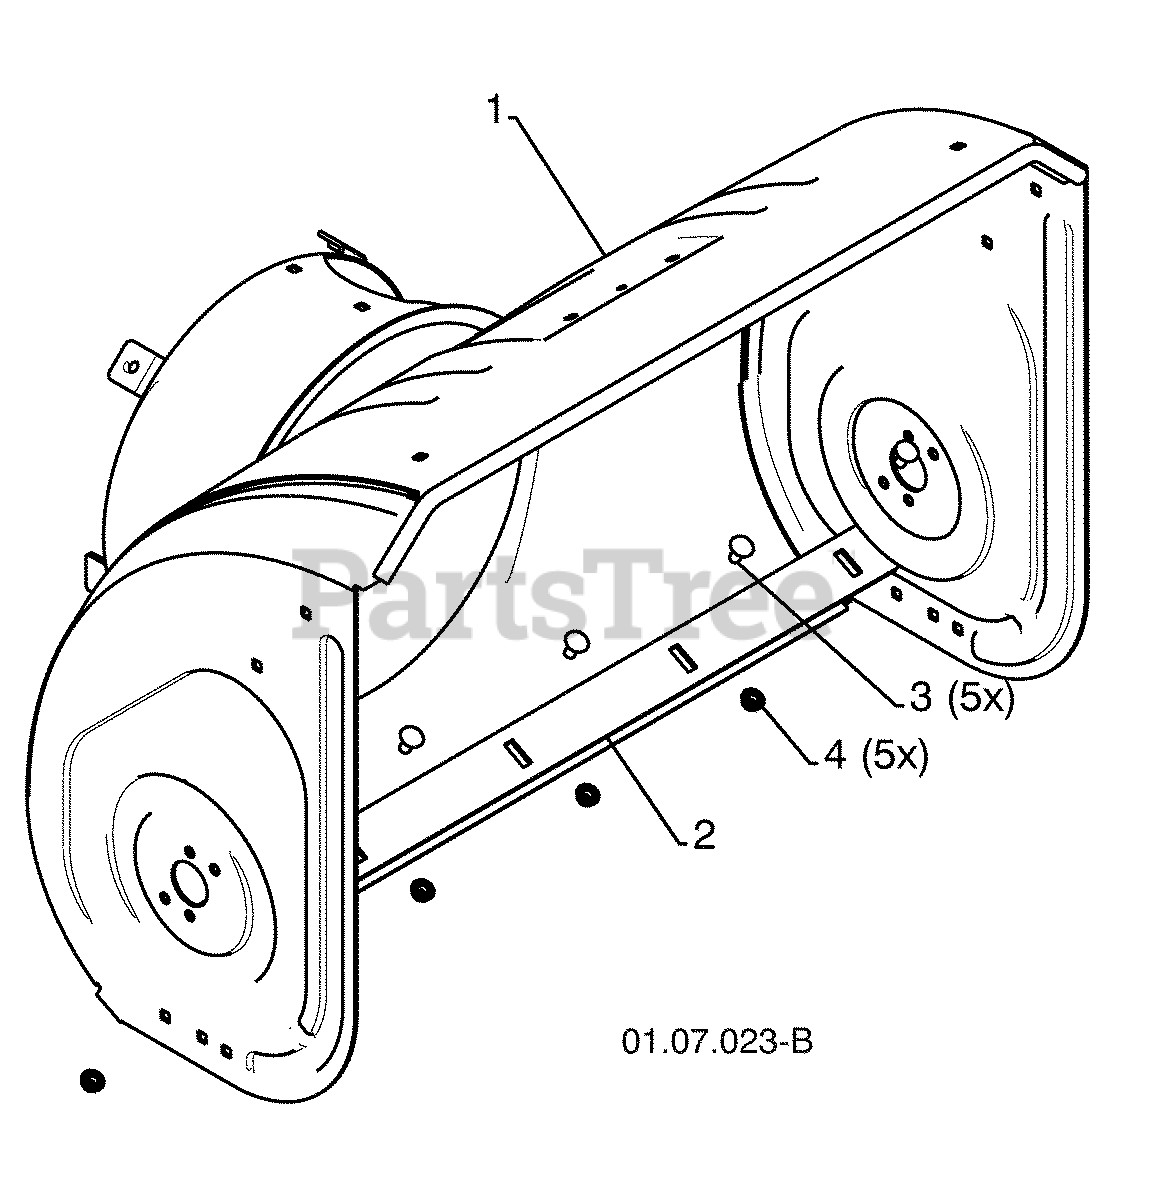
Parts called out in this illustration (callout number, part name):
1	AUGER HOUSING
2	SCRAPPER BAR
3	CARRIAGE BOLT 5/16-18 X .625
4	NUT 5/16-18
